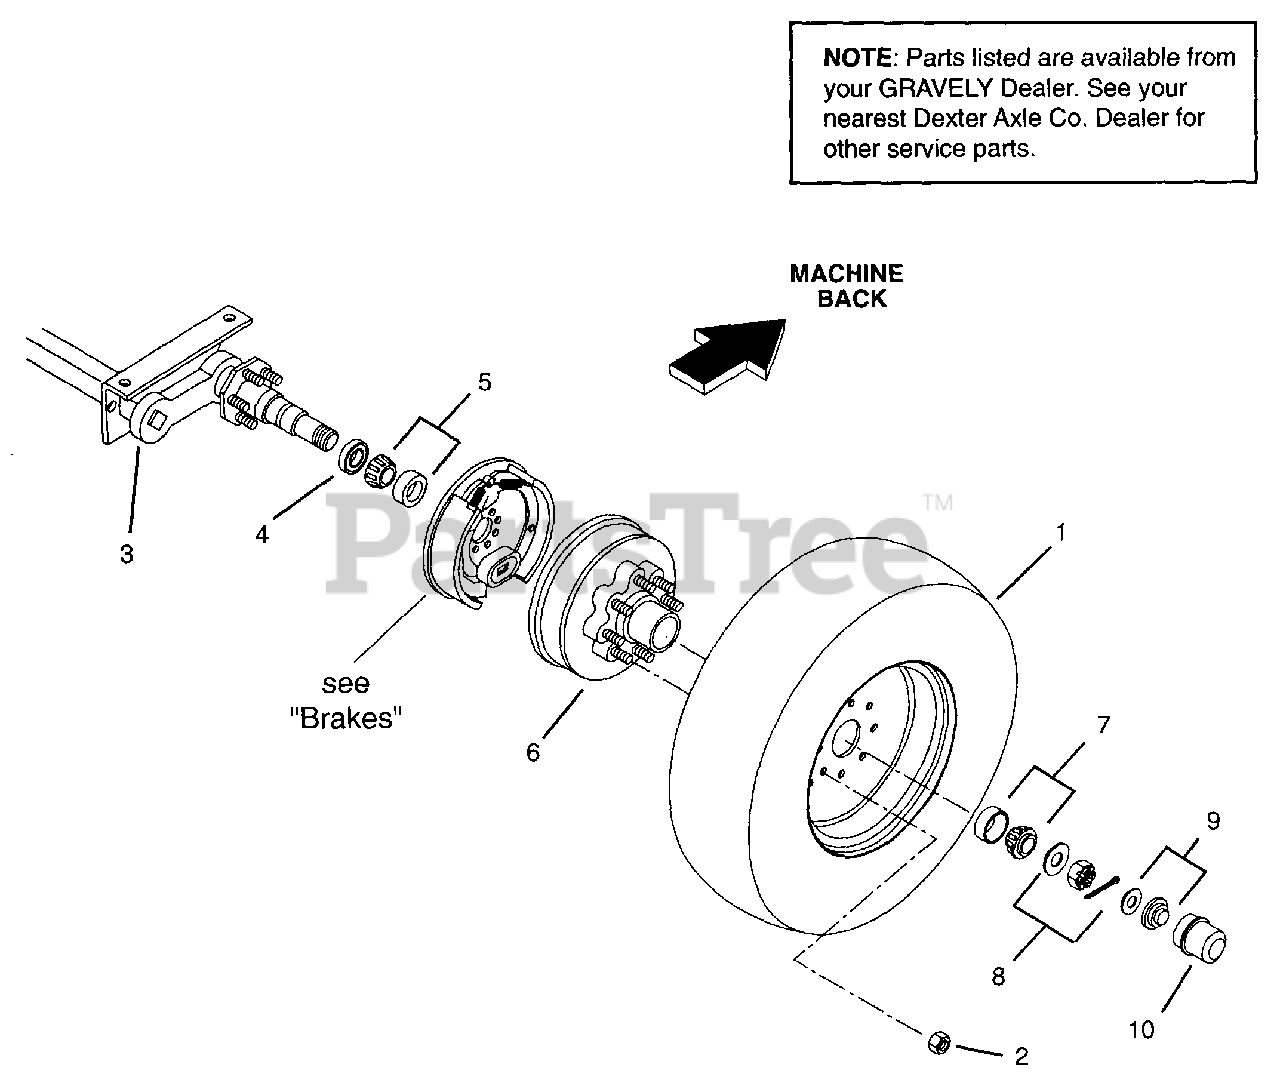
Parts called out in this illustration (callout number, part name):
1	Tire/Rim Assembly
2	Wheel Nut .50-20 13/16 Across Flats Automotive Type
3	Axle-6000lb 8 Lug Hydraulic Surge
3	Axle-6000lb 8 Lug Electric Brake
4	Grease Seal
5	Inner Bearing Cup & Cone
6	Hub & Drum
6	Hub & Drum-Electric
7	Outer Bearing Cup & Cone
8	Hardware Kit
9	Plug Kit
10	Grease Cap
